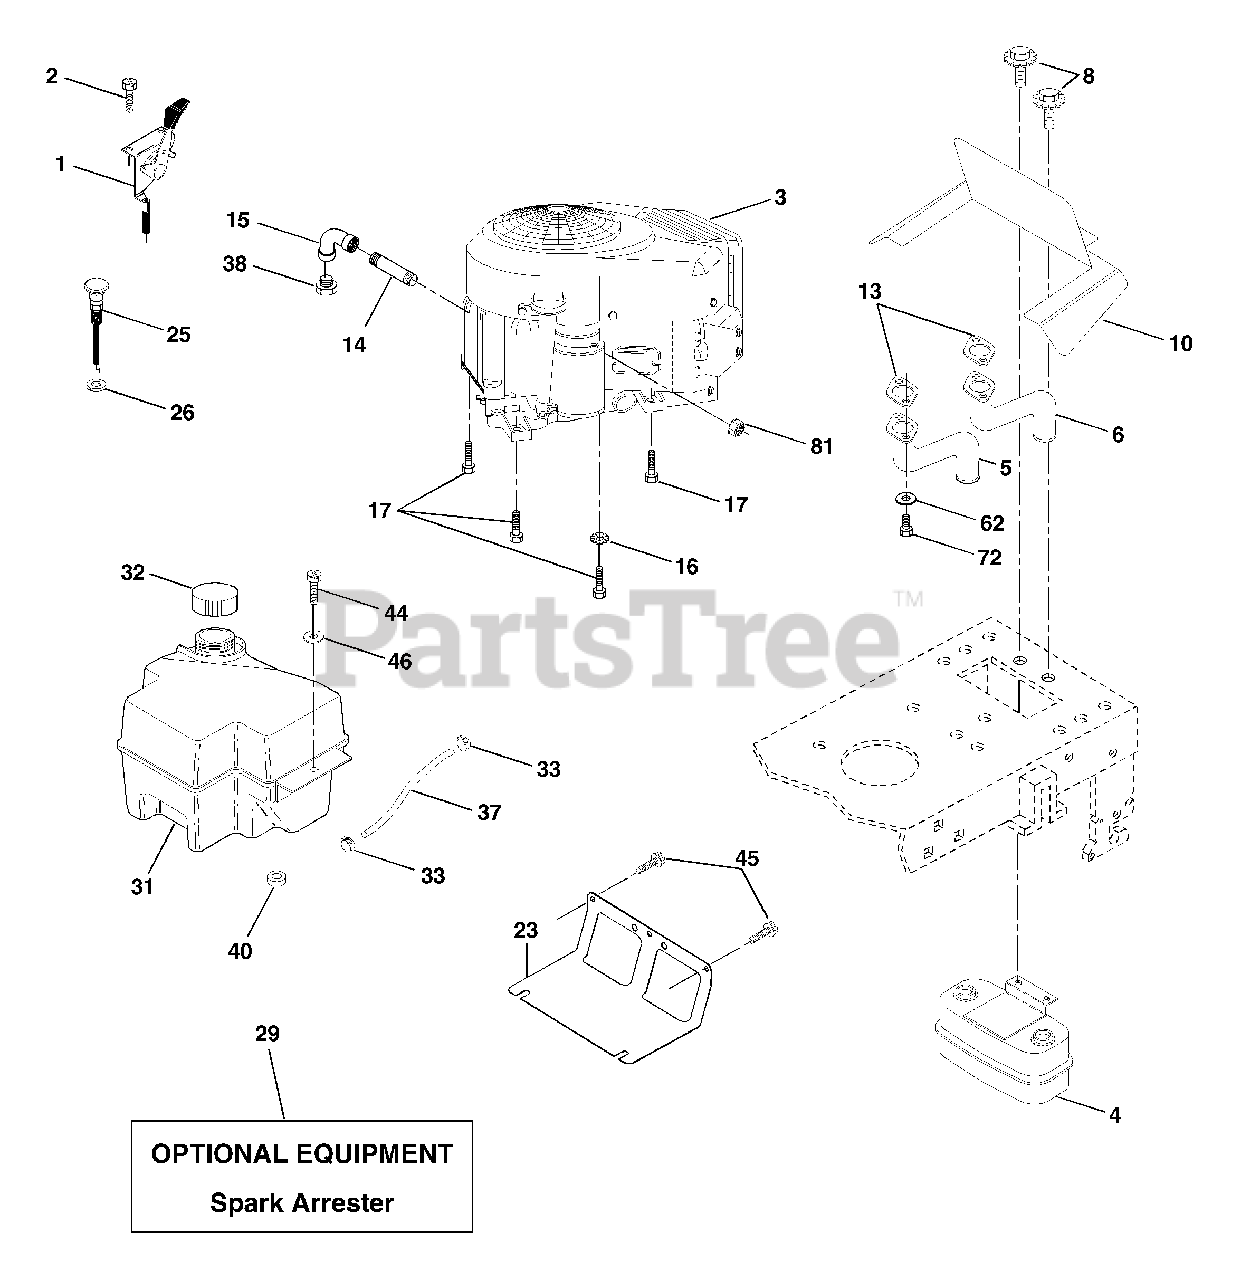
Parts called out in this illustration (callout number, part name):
1	Control, Throttle
2	Screw Hex Thd Cut 1/4-20 x 5/8
4	Muffler, Asm. Twin Lo-Tone
5	Pipe Exhaust Intek 20 RH
6	Pipe Exhaust Intek 20 LH
8	Bolt 5/16-18 UNC x 3/4
10	Shield Browing B&S Intek II
13	Muffler Gasket
14	Nipple, Pipe
15	Elbow, Standard 90°, 3/8-18 NPT
16	Washer, Lock Ext tooth 3/8
17	Screw Thdrol 3/8-16 x 1-1/2
23	Shield, Browning/Debris Guard
25	Control Choke
26	Nut Keps 3/8-24 UNF
29	Arrester, Spark
31	Tank, Fuel
32	Cap Gauge, Fuel
33	Clamp, Hose Blk
37	Line, Fuel
38	Plug, Oil Drain
40	Bushing Snap Nyl Blk Fuel Line
44	Screw Hexwsh Thdrol 1/4-20 x 3/4
45	Screw Hex Wsh Thdrol 3/8-16 x 3/4
46	Washer 9/32 x 7/8 x 16 Ga.
62	Washer Lock Hvy Hlcl Spr 5/16
72	Screw Hex Hd Cap 5/16-18 x 3/4
81	Nut Keps Hex 1/4-20 Unc
